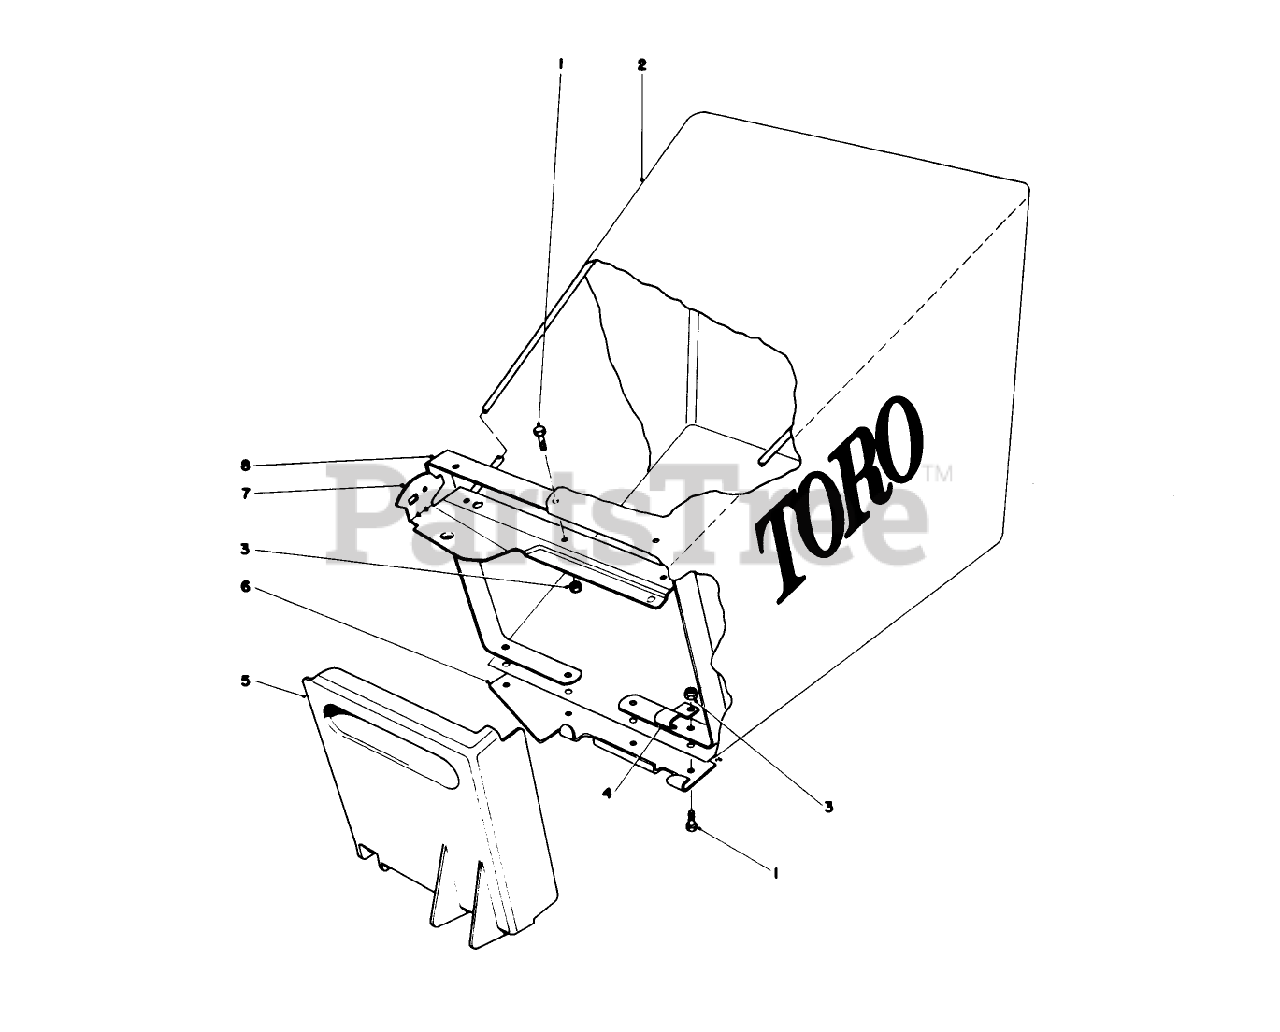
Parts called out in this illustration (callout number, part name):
1	SCREW-HWH
5	BAG DOOR
7	BAG FRAME ASM
8	LOWER BAG FRAME
